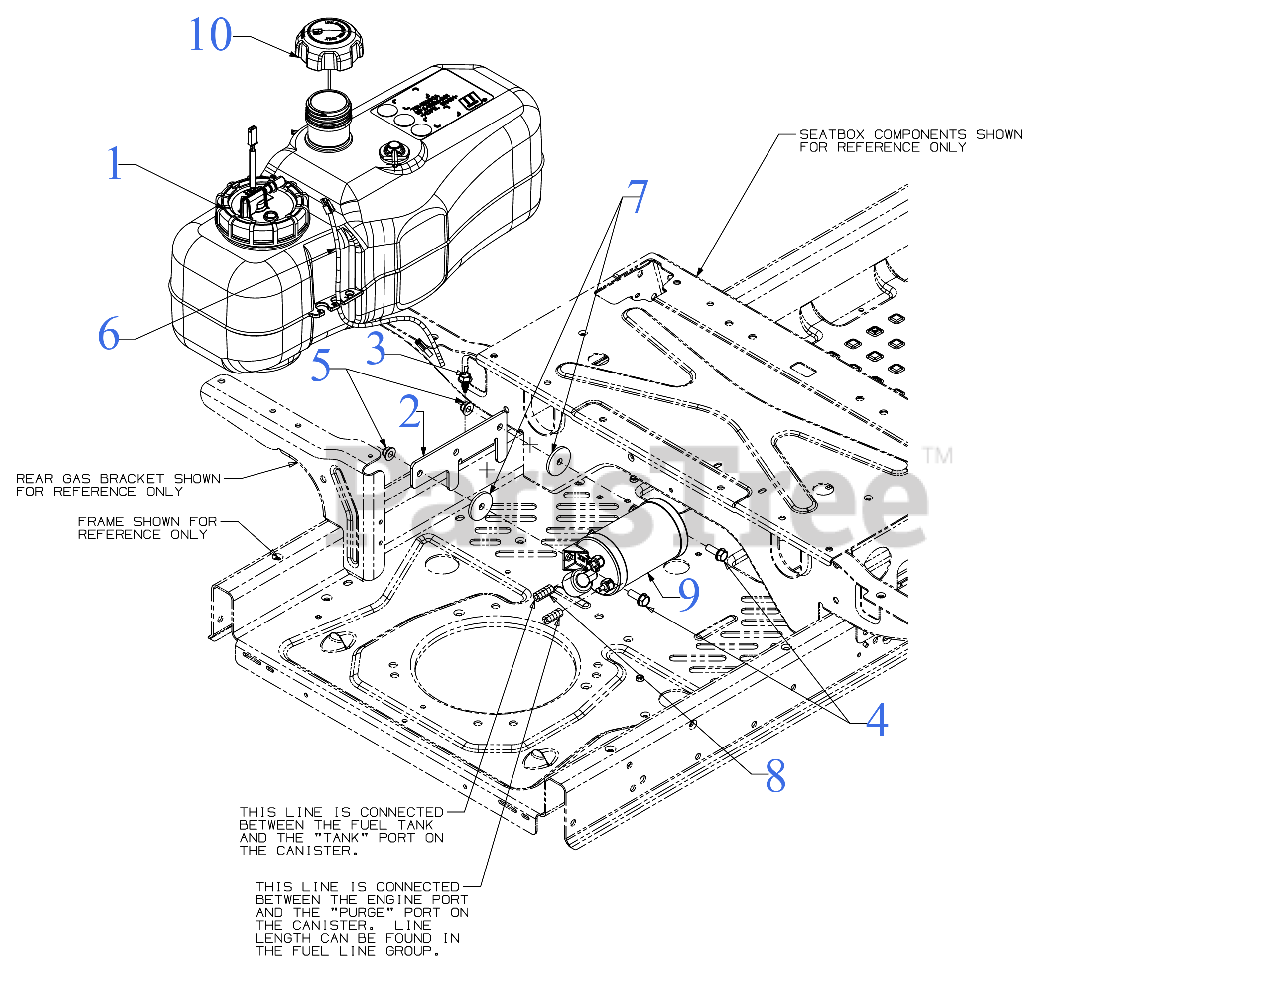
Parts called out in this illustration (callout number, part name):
1	FUEL TANK ASSEMBLY
2	CARBON CANISTER BRACKET (POWDER BLACK)
3	SCREW 5/16-18 x .750
4	SCREW 5/16-18 x .875 GR5
5	FLANGE LOCK NUT 5/16-18
6	JUMPER HARNESS
7	FLAT WASHER
8	FUEL HOSE LO PERMEATION 28"
9	CARBON CANISTER
10	FUEL CAP (W/TETHER)
